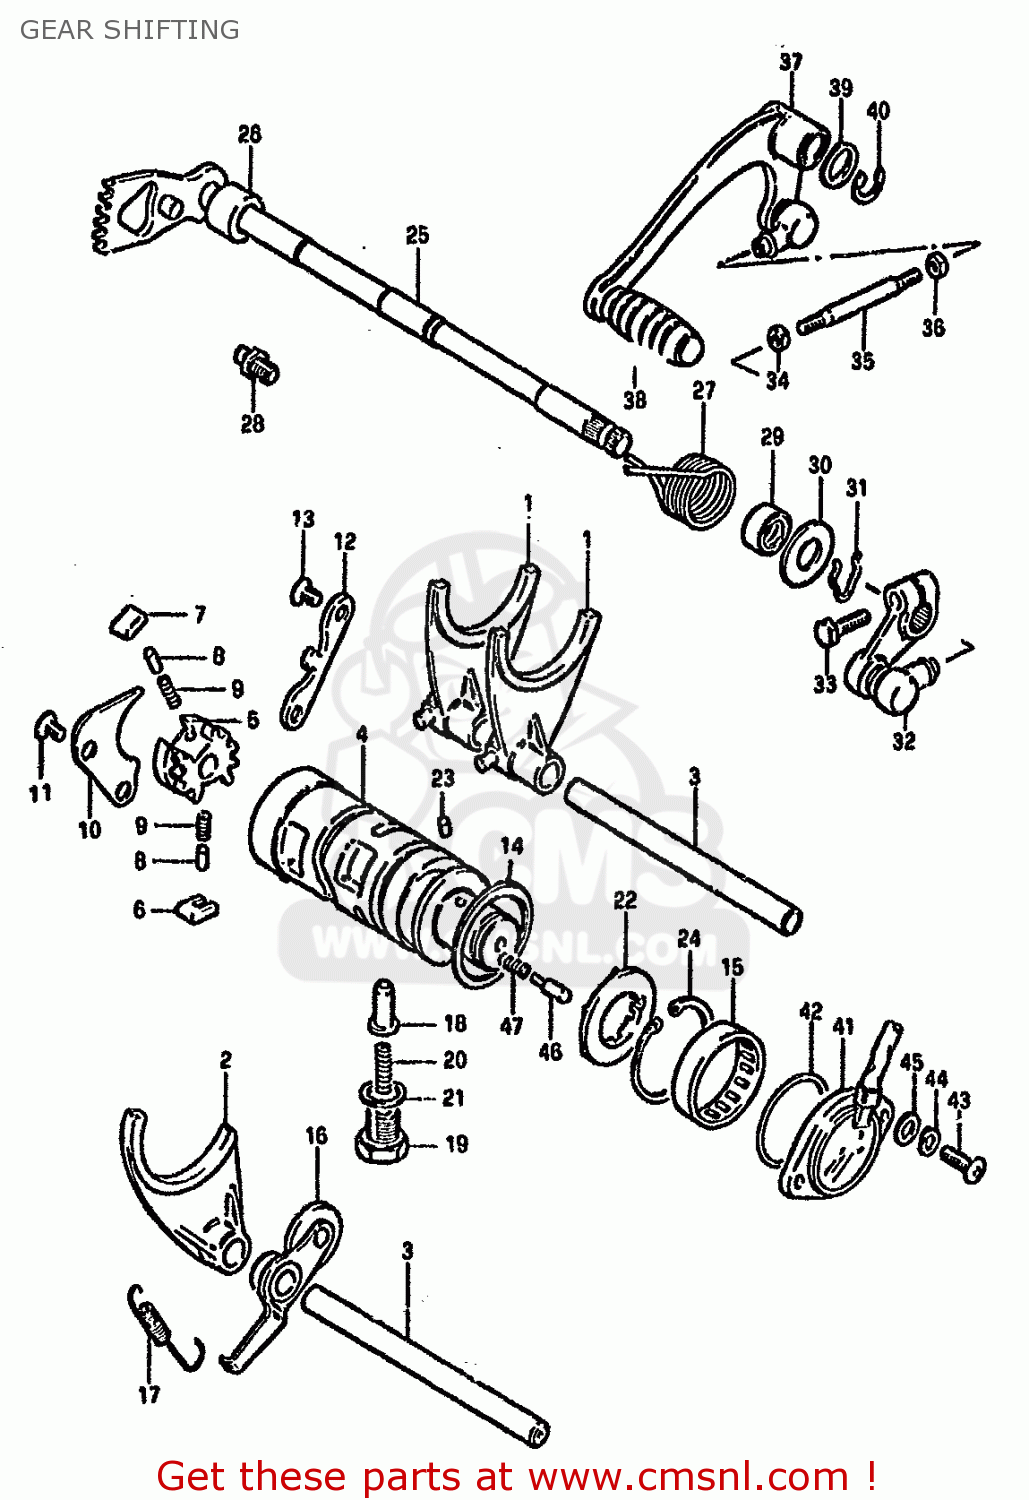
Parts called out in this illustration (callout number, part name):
1	FORK,GEAR SHIFT NO.1
2	FORK,GEAR SHIFT NO.3
3	SHAFT,GEAR SHIFT FORK
4	CAM,GEAR SHIFT
5	RETAINER,GEAR SHIFT CAM
6	PAWL,GEAR SHIFT NO.1
7	PAWL,GEAR SHIFT NO.2
8	PIN(5X8)
9	SPRING
10	LIFTER,GEAR SHIFT PAWL
11	SCREW
12	GUIDE,GEAR SHIFT CAM
13	SCREW
14	WASHER(40X45X1)
15	BEARING(25X32X12)
16	STOPPER,GEAR SHIFTING
17	SPRING
18	STOPPER,GEAR SHIFT CAM NO.2
19	HOLDER,GEAR SHIFT CAM STOP SPR
20	SPRING
21	GASKET(14X19.2X2) (NAS)
22	PLATE,GEAR SHIFT CAM STOPPER
23	PIN 4X6
24	CIRCLIP
25	SHAFT,GEAR SHIFT
26	SPACER(12X20X15.3)
27	SPRING
28	STOPPER,GEAR SHIFT CAM
29	OIL SEAL
30	WASHER (12.5X27X1.6)
31	SPRING,RETAINER
32	ARM,GEAR SHIFT LINK
33	BOLT
34	NUT
35	ROD,GEAR SHIFT LINK
36	NUT
37	LEVER ASSY,GEA
38	RUBBER,PEDAL
39	WASHER(12.5X20X1)
40	CIRCLIP
41	TERMINAL BASE,NEUTRAL SWITCH
42	O-RING (D:2.4 ID:26.2)
43	SCREW 5X20
44	LOCK WASHER
45	WASHER
46	PIN(5X15.5)
47	SPRING
